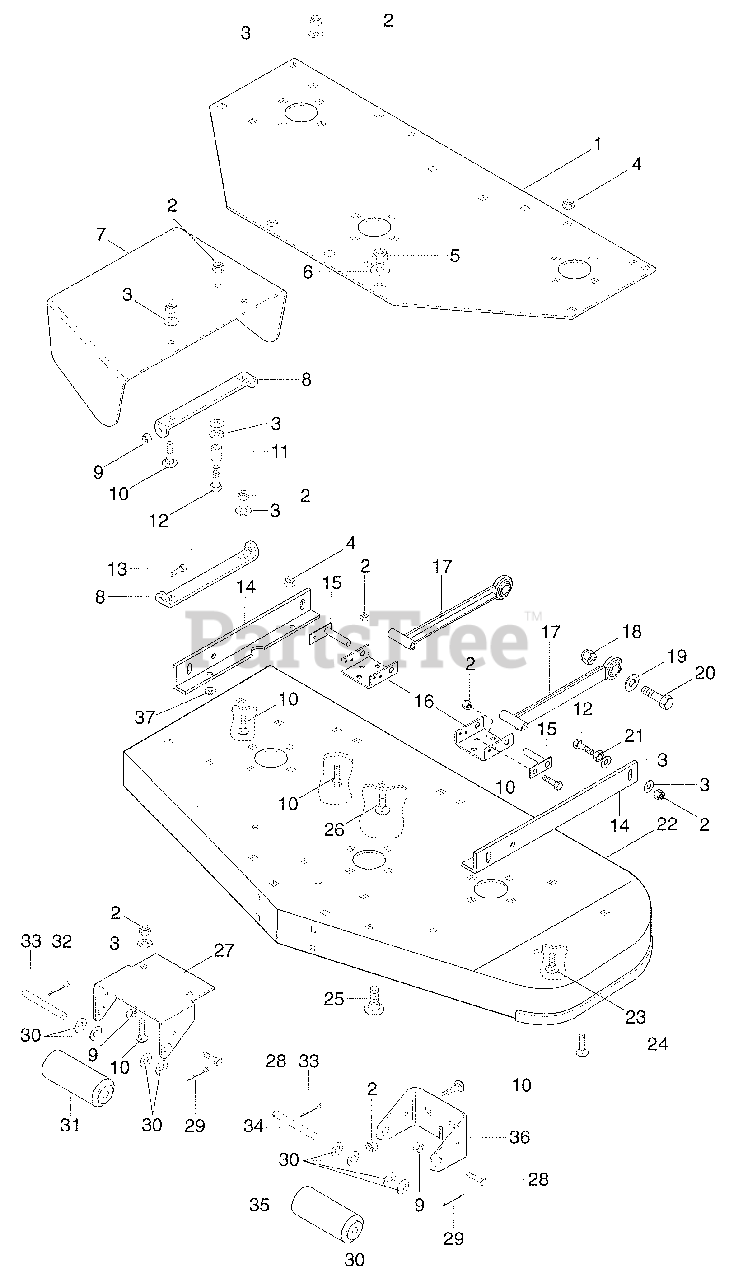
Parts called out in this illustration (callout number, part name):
1	Plate, Support
2	Nut Locking Nylon .375-16 Grade 2
3	Washer Flat Steel .406 X .812 X .065
4	Nut Locking Nylon .312-18 Grade 2
5	Nut Locking Nylon .50-13 Grade 2
6	Washer Flat Steel .531 X 1.250 X .100
7	Shield, Safety External 50" Mower
8	Bracket, Chute
9	Nut Locking Nylon .250-20 Grade 2
10	Bolt Round Head Square Neck .38-16 X 1.0
11	Bushing Sleeve .407 X .625 X .750
12	Bolt Hex .38-16 X 1.50 Grade 5
13	Bolt Hex .25-20 X .875
14	Bracket 50" Mower Mounting LH
15	Weldment, Mower Mounting Pin
16	Bracket, Mower Mounting Rear
17	Weldment, Mower Mounting Arm
18	Nut Locking .875-9
19	Washer Flat Steel .875 X 1.500 X .1196
20	Bolt Hex .87-9 2.75 Grade 5
21	Nut Hex .375-16 Grade 2
22	Weldment, 50" Mower Fabricated
23	Bolt Round Head Square Neck .31-18 X .62
24	Bolt Round Head Square Neck .31-18 X 1.0
25	Bolt Round Head Square Neck .50-13 X 1.00
26	Bolt Round Head Square Neck .375-16 X .75 Grade 1
27	Bracket, Roller RH
28	Bolt Hex .25-20 X .75 Grade 5
29	Pin Cotter .250 X 2.00
30	Washer Flat Steel .656 X 1.312 X .095
31	Roller, Gage
32	Pin Cotter .25 X 1.00
33	Shaft, Center Roller
35	Roller, Gage
36	Bracket, Roller
37	Bushing .406 X .750 X .188
